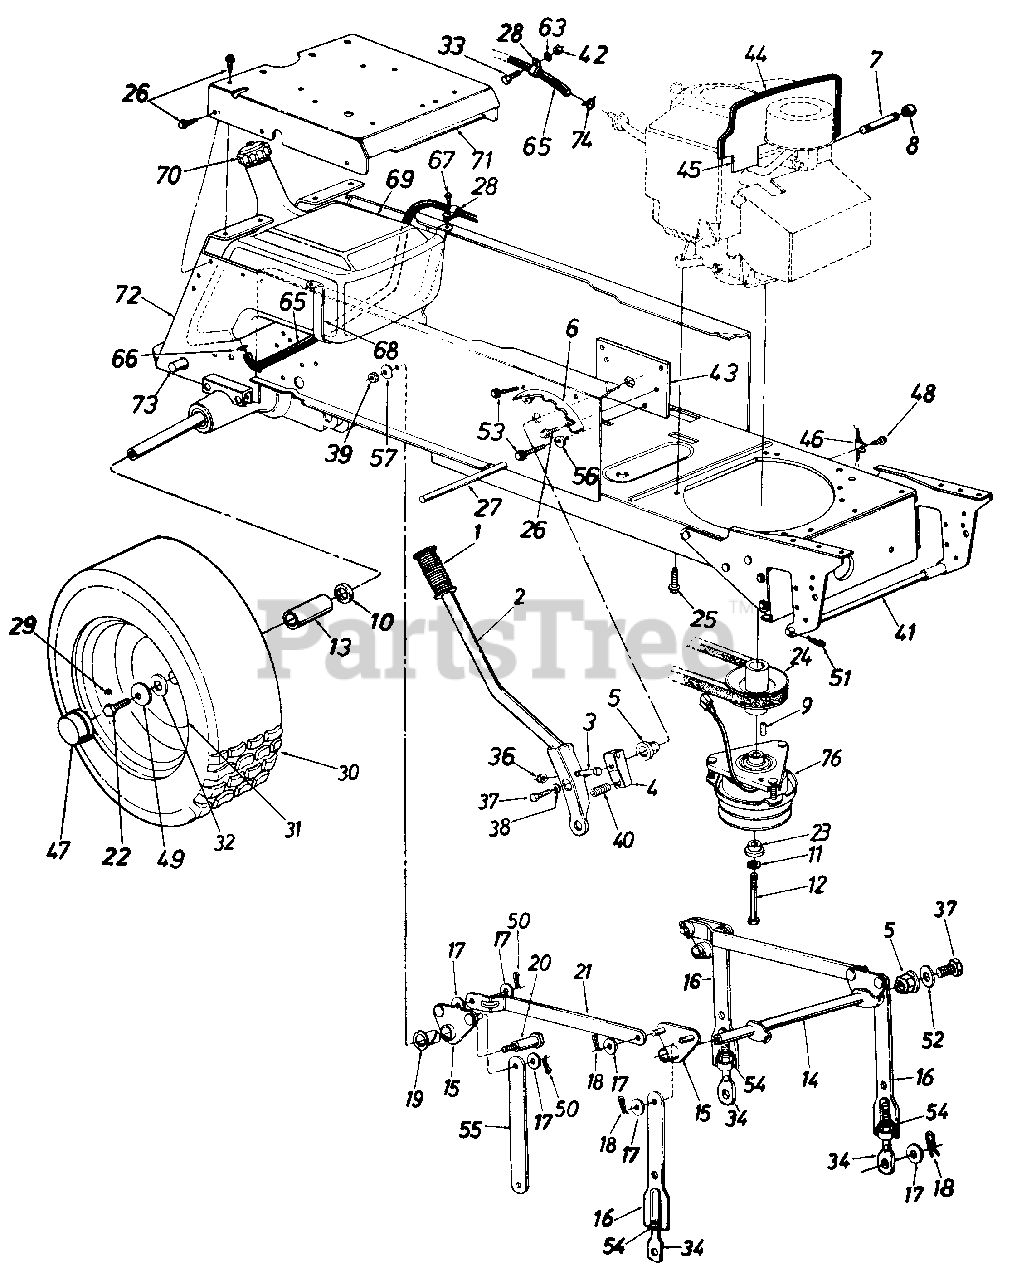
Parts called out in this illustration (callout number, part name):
1	Grip
2	Lift Handle Ass'y.
3	Hex Bolt 5/16-18 x 1.5" Lg.
4	Lift Shaft Drive
5	Plastic Hex Brg. 518" I.D.
8	Pipe Cap 3/8-18 Npt.
9	Sq. Key 1/4" x 1/4" x 1.50" Lg.
10	Fl-Wash. .76" I.D. x 1.49" O.D.
11	L-Wash. 7/16" I.D.
12	Hex Bolt 7/16-20 x 3.75" Lg.
13	Sleeve .75" I.D. x 1.0" O.D.
14	Lift Shaft Ass'y.
15	Lift Pivot 8rkt. Ass'y.
17	Fl-Wash. 112" I.D. x 1.00" O.D. x .090"
18	Hairpin Cotter
19	Nyliner 518" I.D. x .88" Lg.
20	Shld. Bolt 518" Dia. x .96" Lg. 3/8-16
23	Shoulder Spacer
24	Engine Pulley
25	Hex Wash. Hd. Scr. 3/8-16 x 1.25" Lg.
26	Hex Thd. Rolling Scr. 5/16-18 x.75" Lg.
27	Running Board Rod
28	Clamp
29	Air Valve
30	Rear Wheel Ass'y. Comp.
31	Rear Wheel Rim Only
32	Flat Washer .34" I.D.
33	Hex Bolt 1/4-20 x .62" Lg.
34	Eye Bolt Adj. Link 1/2-13 Thd.
36	Hex Cent. L-Nut 5/16-18 Thd.
37	Hex Scr. 5/16-24 x .62" Lg.
38	L-Wash. 5/16" I.D.
39	Hex Top L-Nut 3/8-16 Thd.
40	Compression Spring
41	Deck Connecting Rod
42	Hex Nut 1/4-20 Thd.
45	Heat Shield
46	Mounting Clamp
47	Hubcap
48	Hex Wash. Hd. TT-Tap Scr. 1/4-20 x .5" Lg.
49	Bell-Wash. .39" I.D.
50	Cotter Pin .09 Dia. x 1.0" Lg.
51	Int. Cotter Pin
52	Flat Wash. .34" I.D. x 1.12" O.D. x .125"
53	Hex Wash. Hd. AB-Tap Scr. 5/16-24 x .5" Lg.
54	Hex Nut 1/2-13 Thd.
56	Fl-Wash..344" I.D.
57	Bell-Wash. .4" I.D. x 1.13" O.D.
63	L-Wash. 1/4" I.D.
65	Fuel Line 50" Lg.
66	Hose Clamp
67	Hex AB-Tap Scr. 1/4 x .62" Lg.
68	Fuel Tank Strap
69	Gas Tank
70	Gas Gauge
71	Seat Plate
74	Hose Clamp
76	Electric Clutch
